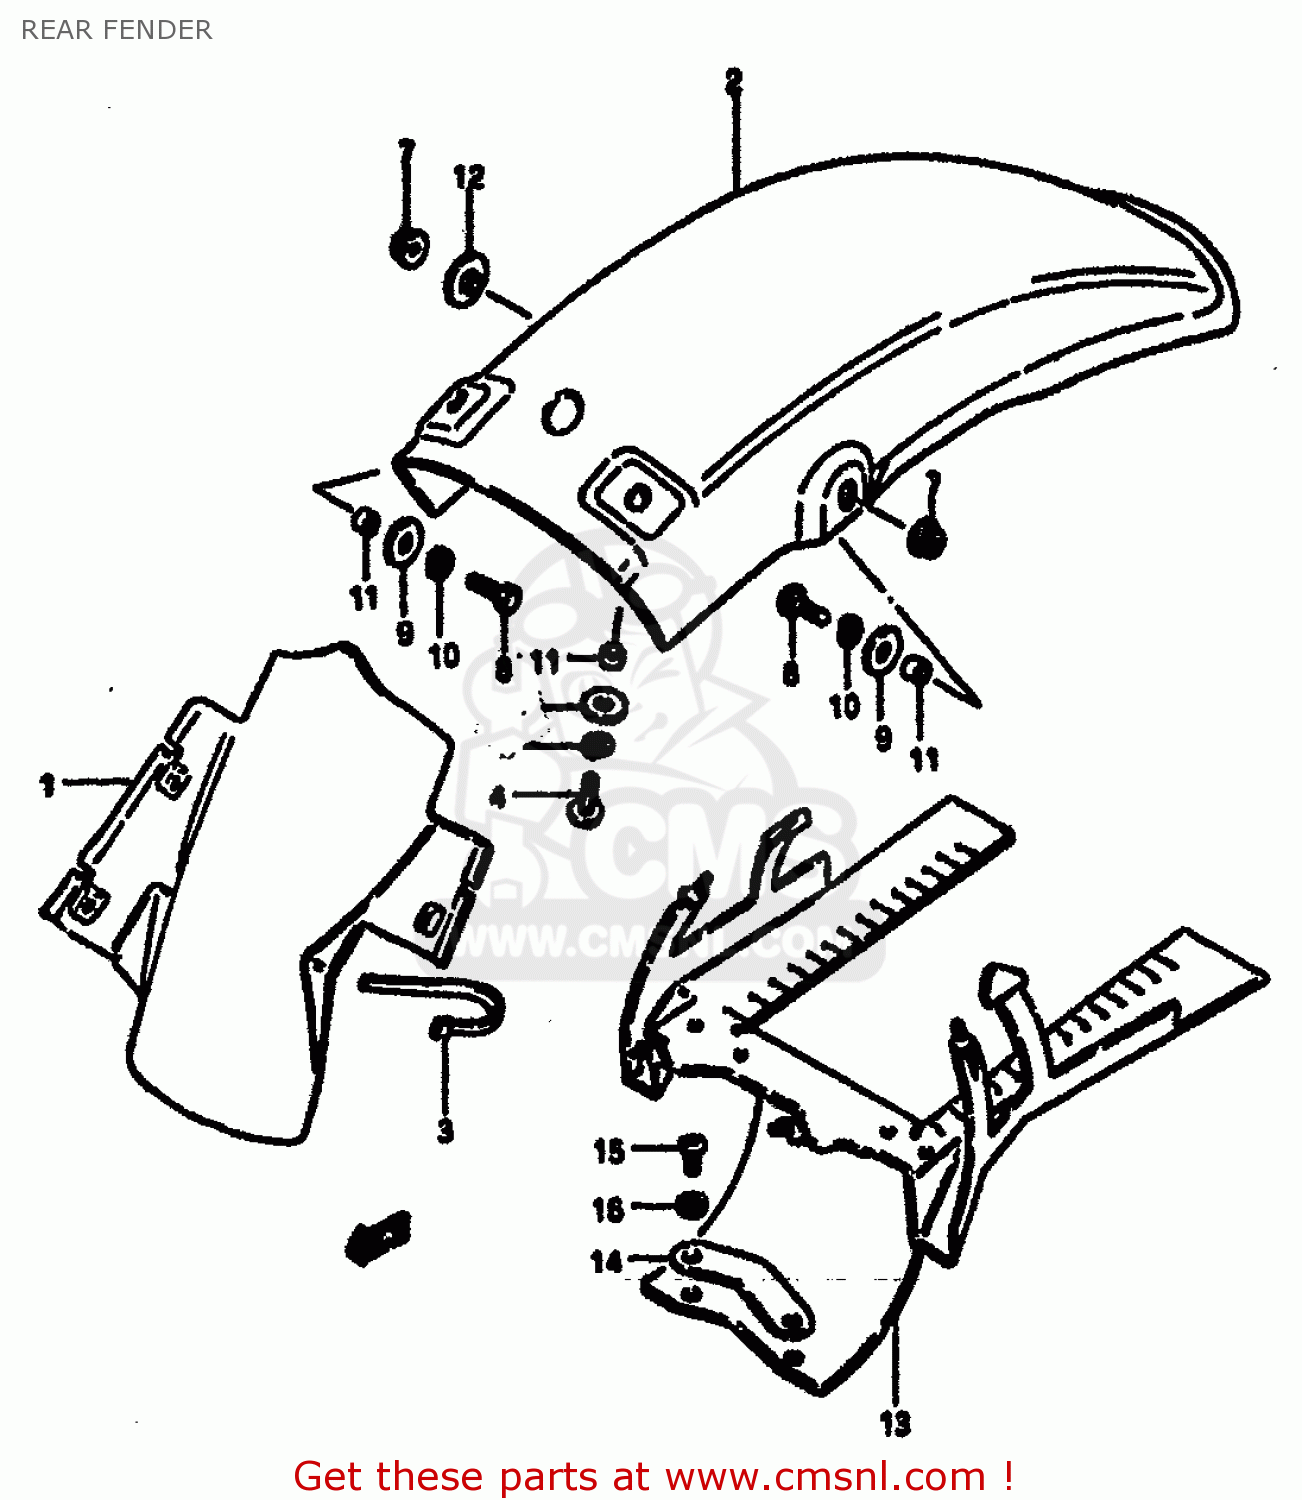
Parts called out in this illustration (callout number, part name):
1	BODY,REAR FENDER,FRONT
2	FENDER,REAR
3	CLAMP
4	SCREW
5	WASHER
6	LOCK WASHER
7	NUT
8	BOLT
9	WASHER (6.5X20X1.2)
10	LOCK WASHER
11	SPACER
12	WASHER
13	MUD GUARD,REAR FENDER
14	PLATE,MUD GUARD
15	SCREW
16	WASHER,5MM
